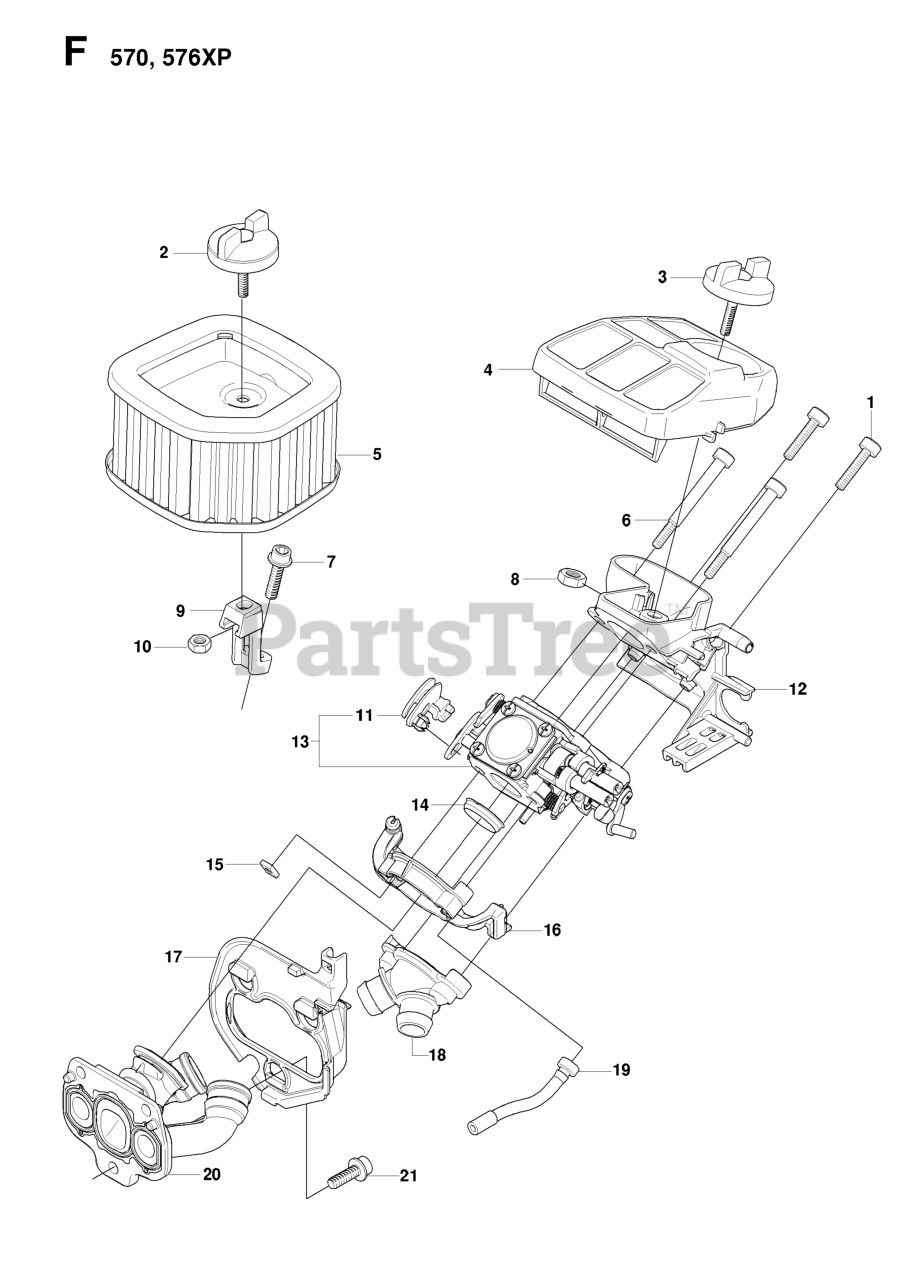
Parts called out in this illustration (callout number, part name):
4	%AIR FILTER
4	RP AIR FILTER
5	AIR FILTER HD 44
5	AIR FILTER
5	AIR FILTER WINTER
6	SCREW 4X46
12	FILTER HOLDER
13	RP CARBURETOR
